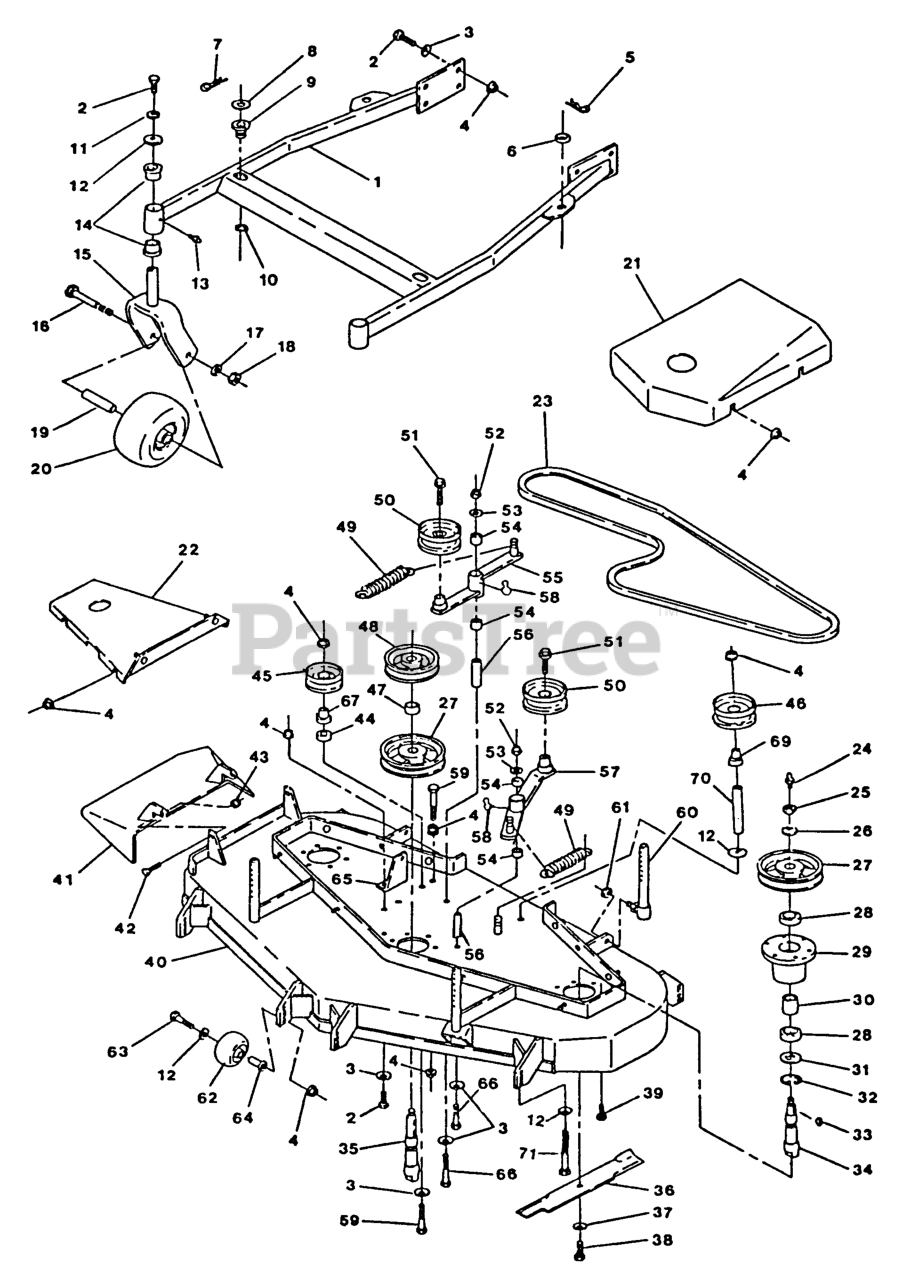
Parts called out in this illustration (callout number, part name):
5	PIN,HAIR COTTER
8	WASHER-FLAT
9	BUSHING-DECK
23	BELT,BLADE DRIVE
26	WASHER-SPRING
27	SHEAVE,BLADE DRIVE
30	SPACER,BEARING
31	SEAL,MECHANICAL DUST
32	RING,SNAP WLDS N5000-244
34	SPINDLE-OUTER BLADE
35	SPINDLE-CENTER BLADE
37	WASHER-SPRING
39	SCRW,TPTTE HH
41	WLD,CHUTE DISCHARGE
46	PULLEY-IDLER
47	SPACER-TUBE
48	SHEAVE,MOWER DRIVE
49	SPRING-EXTENSION
50	IDLER,PULLEY
54	SLEEVE-BEARING
55	ASM,IDLER ARM
56	BUSHING-PIVOT, IDLER
57	ASM,IDLER ARM
62	ROLLER-SCALP, ANTI
63	SCRWCAPHH
64	BUSHING-ROLLER
65	BRACKET,SPRING ANCHOR
66	SCREW-HH
67	BUSHING-IDLER
68	NUT-WING
69	BUSHING,IDLER
70	SPACER-FENDER
